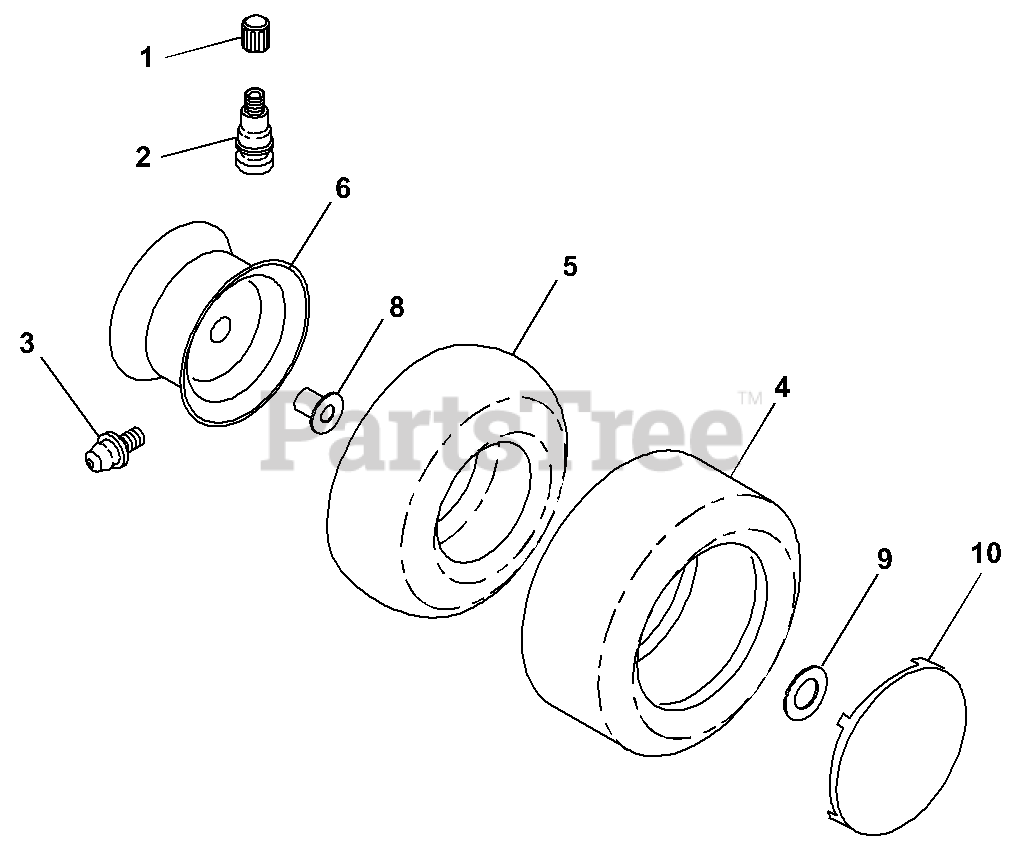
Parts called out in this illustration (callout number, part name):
1	Cap, Valve Stem
2	Stem, Valve
3	Fitting, Grease
4	Tire, Front
4	Tire, Rear
5	Tube, Front Tire
5	Tube, Rear Tire
6	Rim, Front
8	Bearing Flange
9	Washer 25/32 x 1-5/8 x 16 Gauge
10	Wheel cover
10	Sealant, Tire (10oz. Tube)
